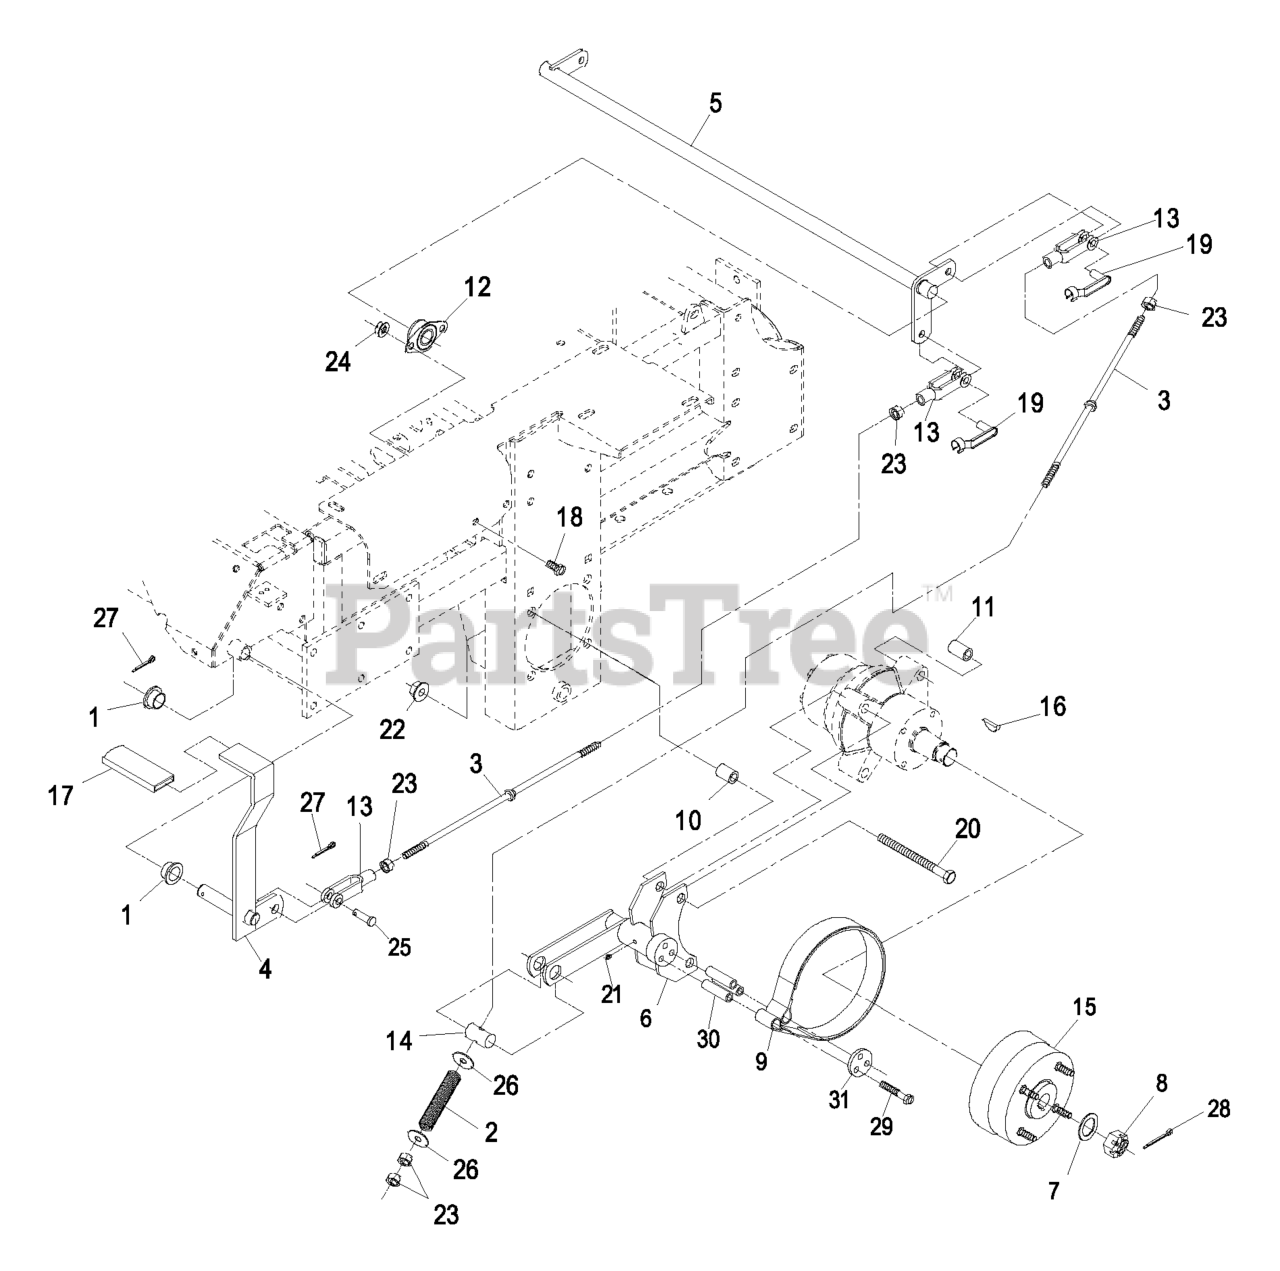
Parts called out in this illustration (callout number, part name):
1	BEARING-CONTROL
2	SPRING-BRAKE
3	ROD-BRAKE
4	BRAKE LEVER ASM
5	SHAFT-BRAKE
6	BRACKET-BRAKE
6	BRAKE BRACKET ASM
7	WASHER-SPACER
9	BAND,BRAKE
10	SPACER-WHEEL, SHORT
11	SPACER-WHEEL, LONG
12	BEARING-FLANGE, SIDE
13	YOKE-LINKAGE, BRAKE
14	PIN-TRUNION
15	WHEEL HUB ASM
16	KEY-WOODRUFF
17	GRIP-LEVER
18	SCREW-HH
19	PIN-SPRING, CLEVIS
20	SCREW-HH
21	FITTING-STRAIGHT
22	NUT-HHF
23	NUT-HEX
24	NUT-HHF, WHIZ
25	PIN-CLEVIS
26	WASHER-FLAT
27	PIN-COTTER
28	PIN-COTTER
29	SCREW-HH
31	RETAINER-BAND, BRAKE
